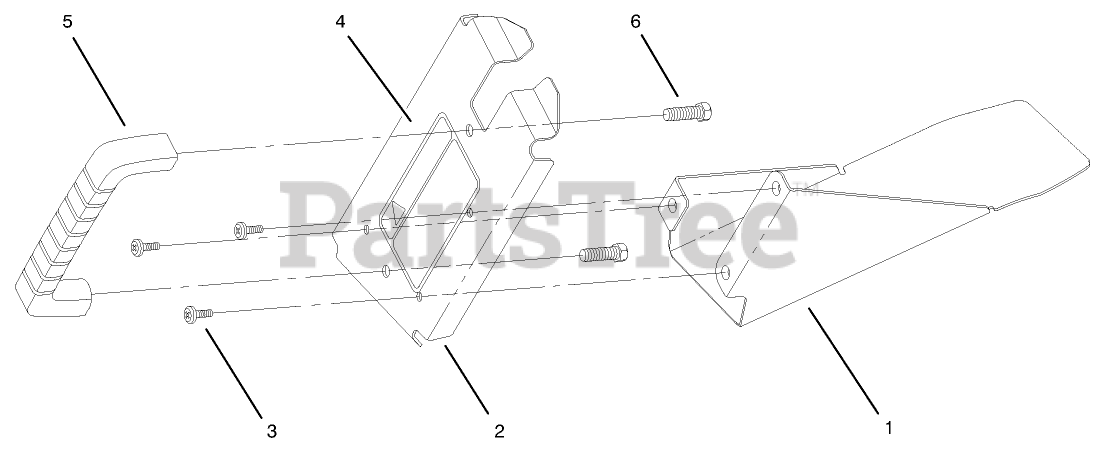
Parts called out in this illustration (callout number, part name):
4	DECAL - WARNING
5	HANDLE-DOOR
6	SCREW-HWH
